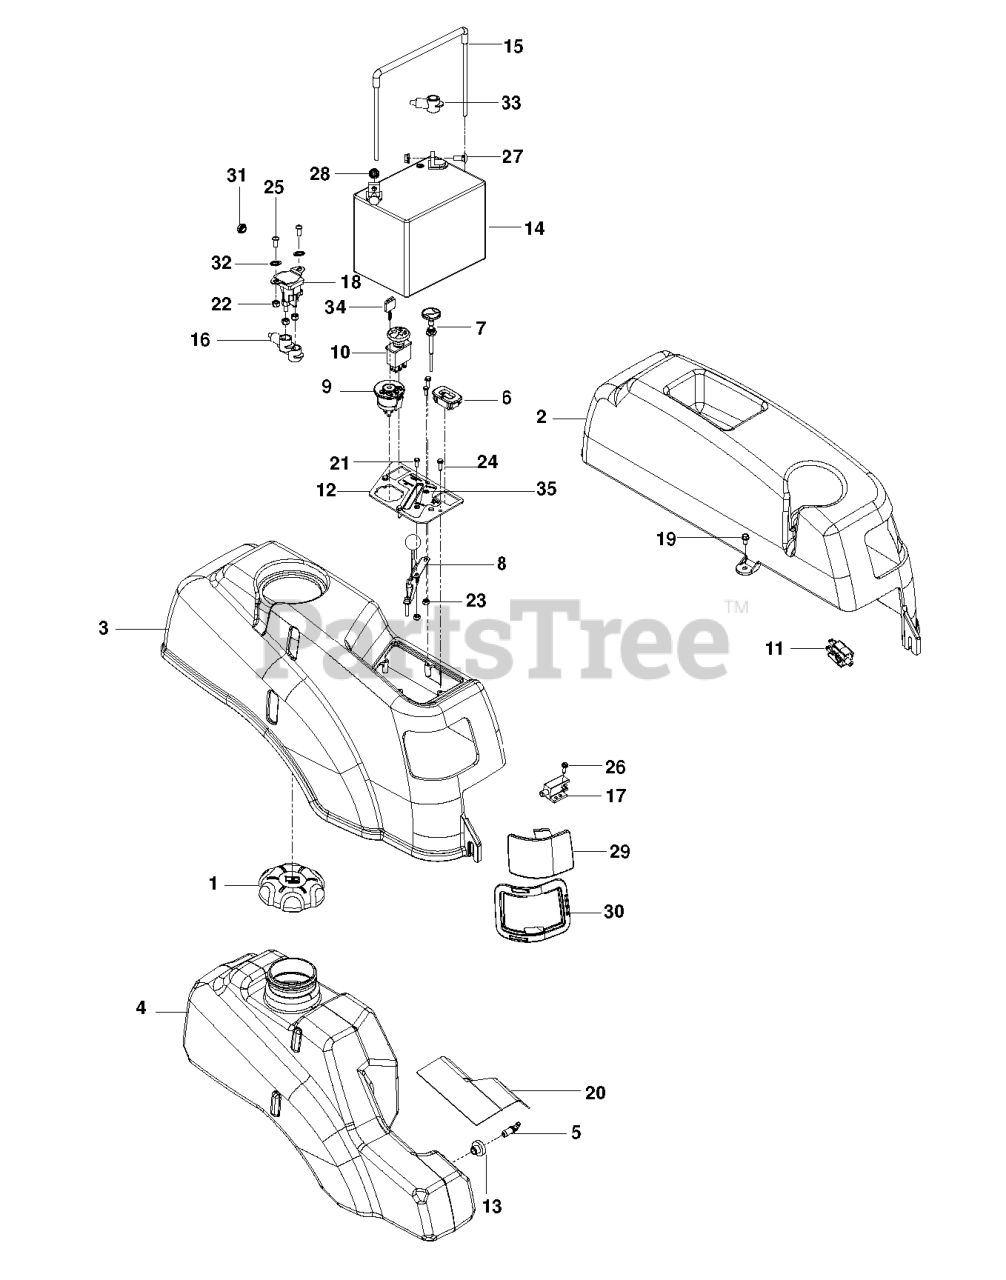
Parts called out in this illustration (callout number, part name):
1	FUEL CAP, HTC
2	FENDER, LT
3	RP.FENDER, RT
4	TANK, FUEL
5	STEM, FUEL TANK
6	HOUR METER
7	CHOKE CONTROL
8	THROTTLE CABLE
9	RP IGNITION SWITCH
10	RP.SWITCH, BLADE
11	SWITCH, BRAKE 3P
12	CONSOLE.PLATE.BLACK
13	RUBBER GROMMET
14	BATTERY, 12 V 330 AMP
15	BATTERY TIE DOWN ASSEMBLY
16	TERMINAL COVER-SM
17	SWITCH, INTERLOCK
19	BOLT 1/4-20 X 1/2 HWST
20	SHIELD, HEAT
21	HCS #10-24 X 1/2
22	NUT.1/4-20.HEX.NYLOC.ZD
23	NUT 10-24 NYLOC
24	SCR #10-12X3/4 HEX WAS HD ZD
25	SCR 1/4-20 X 5/8 BTN SKT HD ZD
26	SCREW #10 X 1/2 SELF TAPPING
27	BOLT 5/16C X 3/4" CARRIAGE
28	5/16-18 NYLOC FLANGE NUT
29	LENS, COLORED LEFT
30	LEFT HEADLIGHT RIM GREY
31	JAM NUT 1/4C (2 2 PW01)
32	WASHER 1/4 INT TOOTH
34	KEY
35	DECAL, IGNITION CONSOLE
